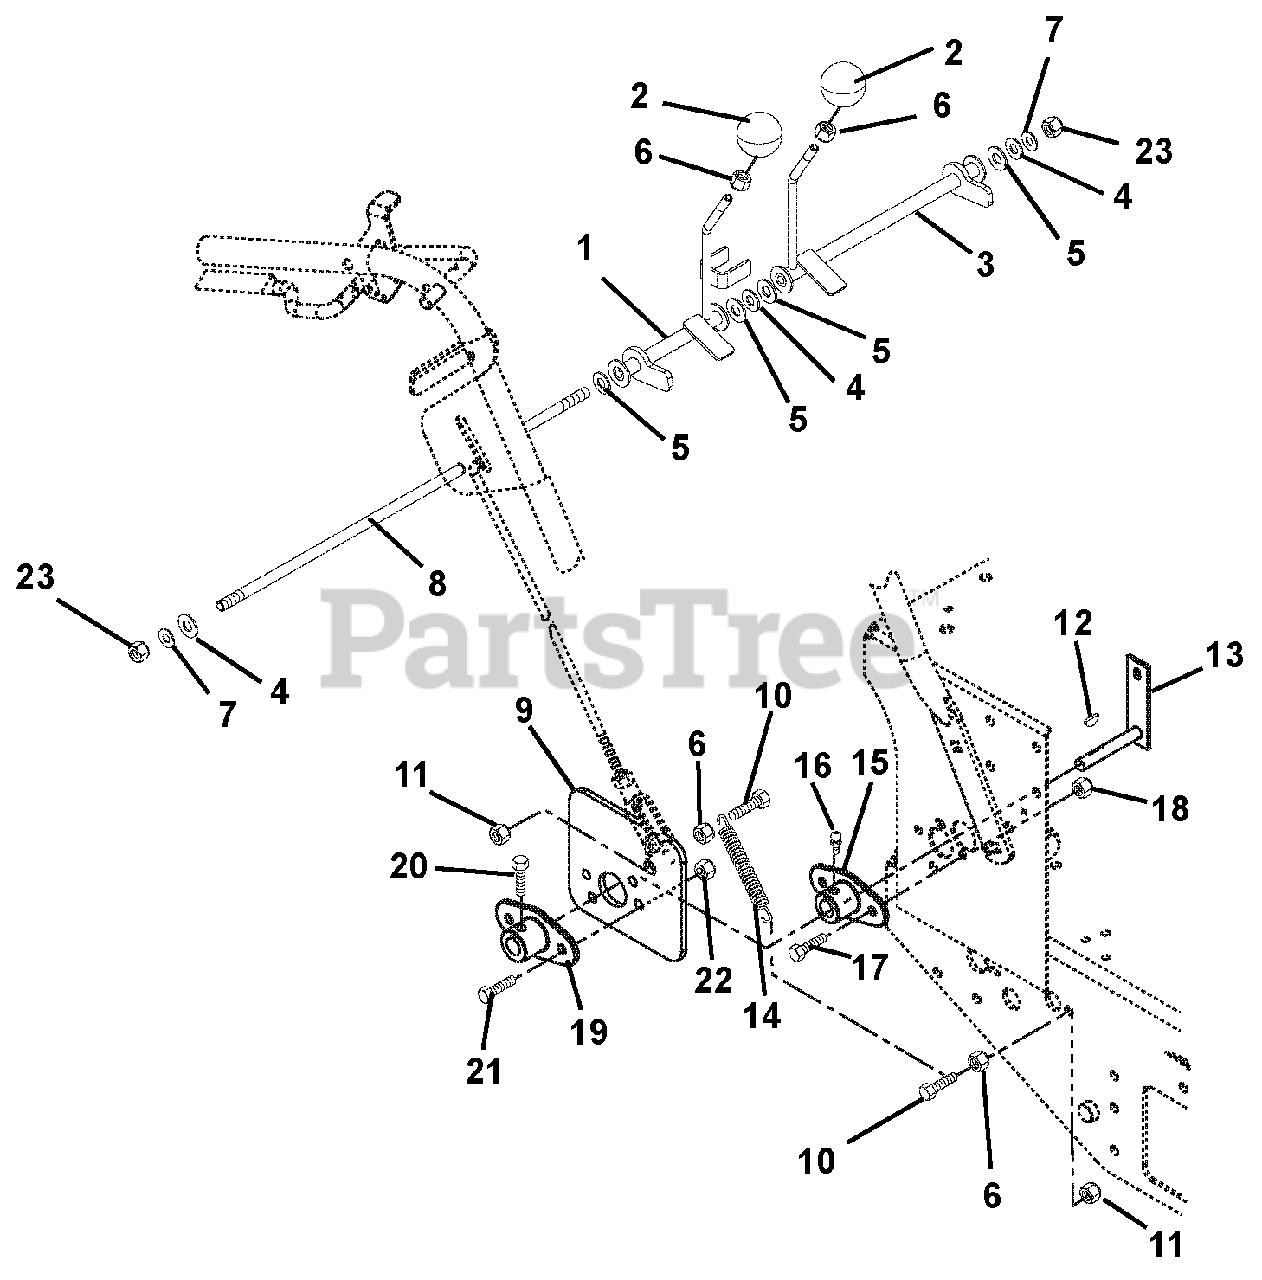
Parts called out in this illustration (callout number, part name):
1	Weldment, Right Hand Lever
2	Knob, Ball-Black 1-13/32, .375-16
3	Weldment, Left Hand Lever
4	Washer, Flat-Steel .406 x .812 x .065
5	Washer, Flat-Nylon .375 x 1.00 x .062
6	Nut, Hex .38-16
7	Washer, Locking .38 x .094 Regular
8	Rod, Speed Control
9	Plate, Speed Control
10	Bolt, Hex .38-16 x 1.50 Grade 5
11	Nut, Locking-Nylon .38-16
12	Key, Woodruff .125 x .75
13	Weldment, Pump Control Left Hand
14	Spring, Tension .105 x 1.00 x 5.0
15	Bushing, Flanged
16	Fitting, Lube .25-28 x .256
17	Bolt, Hex .31-18 x 1.00 Grade 5
18	Nut, Locking-Nylon .312-18
19	Arm, Speed Control
20	Bolt, Hex .25-20 x .50 Grade 5
21	Bolt, Hex .25-20 x .75 Grade 5
22	Nut, Locking-Nylon .25-20
23	Nut, Hex .375-24 Grade 2
